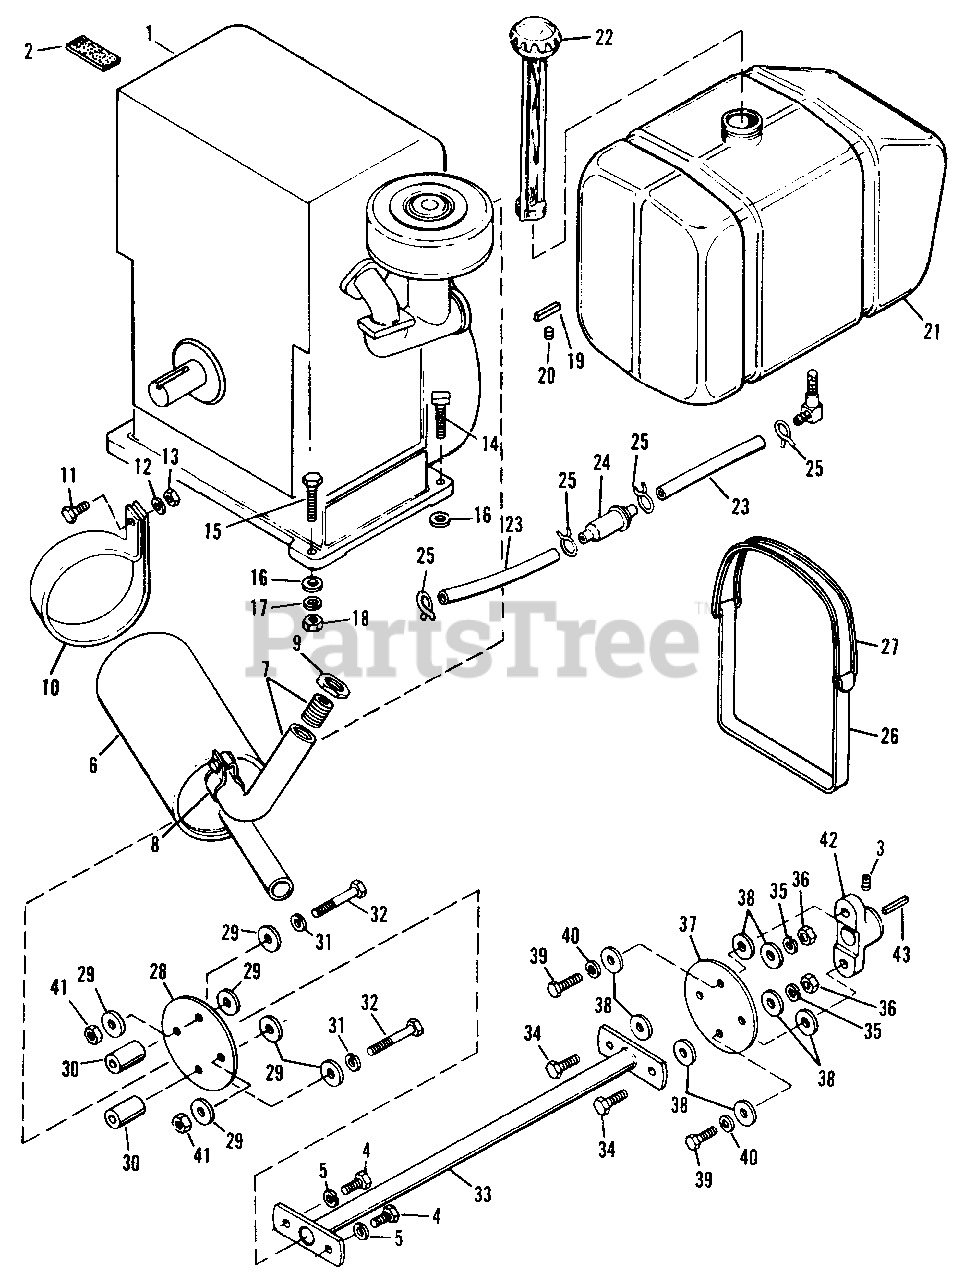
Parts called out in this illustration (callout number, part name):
2	Pad, Fuel Tank
3	Cup Pt. Socket Head Set Screw, 3/8"-24 N.F. x 3/8"
4	Hex Capscrew, 3/8"-16 N.C. x 1-1/8"
5	Lockwasher, 3/8"
6	Muffler, Exhaust
7	Elbow & Nipple Assembly
8	Muffler Clamp
10	Strap, Muffler
11	Hex Capscrew, 5/16"-18 N.C. x 518"
12	Lockwasher, 5/16"
13	Full Hex Nut, 5/16"-18 N.C.
14	Rec't. Head Screw, 3/8"-16 N.C. x 1-5/16"
15	Hex Capscrew, 3/8"-16 N.C. x 1-1/2"
16	Plain Washer, 3/8" Std.
17	Lockwasher, 1/2"
18	Full Hex Nut, 3/8"-16 N.C.
19	KEY, Hi-Pro
20	Cup Pt. Socket Head Set Screw, 5/16"-18 N.C. x 3/8"
21	Tank, Fuel
22	Cap, Fuel Tank
23	Hose, Fuel, Flexible
24	Fuel Filter
25	Clamp, Hose
26	Strap, Tank
27	Strap, Fuel Tank
29	Washer, Special
30	Bearing, Pivot Block
31	Lockwasher, 3/8"
32	Hex Capscrew, 3/8"-16 x 2-1/4"
33	Shaft Assembly, Drive
34	Hex Capscrew, 3/8"-16 x 1-1/8"
35	Lockwasher, 3/8"
36	Full Hex Nut, 3/8"-16
38	Washer, Special
39	Hex Capscrew, 3/8"-16 N.C. x 1-1/8"
40	Lockwasher, 3/8"
41	Full Hex Nut, 3/8"-16 N.C.
42	Flange, Drive Shaft
43	Key, Dive Shaft
